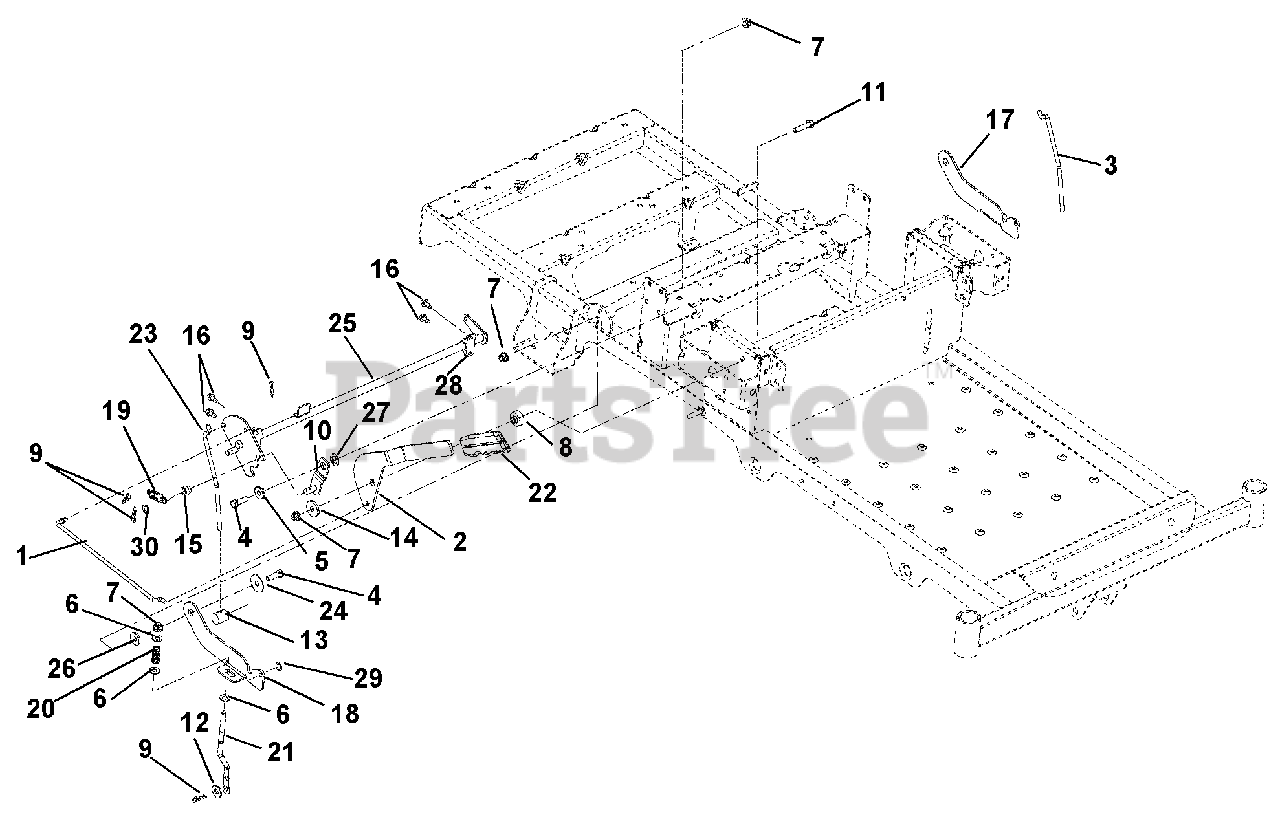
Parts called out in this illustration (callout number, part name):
1	Link, Brake Handle
2	Handle, Parking Brake
3	Link, Neutral Left Hand
4	Bolt, Hex .31-18 x 1.00
5	Bushing, Flange .312 x .500 x .344 x .880
6	Washer, Flat Steel .344 x .688 x .065
7	Nut, Flange Nyloc 5/16-18
8	Spacer, Brake Handle
9	Pin, Hair Internal .08 x .18 x 1.18
10	Weldment, Detent Arm
11	Bolt, Hex .31-18 x 1.25
12	Washer, Flat Steel .38 x .875 x .083
13	Trunnion, 1/4-20
14	Washer, Flat Steel .344 x 1.125 x .135
16	Screw, Tapping .25-20 x .50 Hex Washer Head
17	Latch, Left Hand Neutral
18	Latch, Right Hand Neutral
19	Spring, Tension .072 x .565 x 1.87
20	Spring, Compression
21	Link, Brake Cog
22	Grip, Parking Brake
23	Link, Neutral Right Hand
24	Washer, Flat Steel .347 x 1.254 x .048
25	Weldment, Brake Shaft
26	Bushing, Flange .325 x .499 x .26 x .88
27	Washer, Flat Steel .52 x .827 x .062
28	Bushing, .50 Clamp Block Molded
29	Ring, Retaining, External .250 x .025
30	Washer, Steel .385 x .745 x .030
